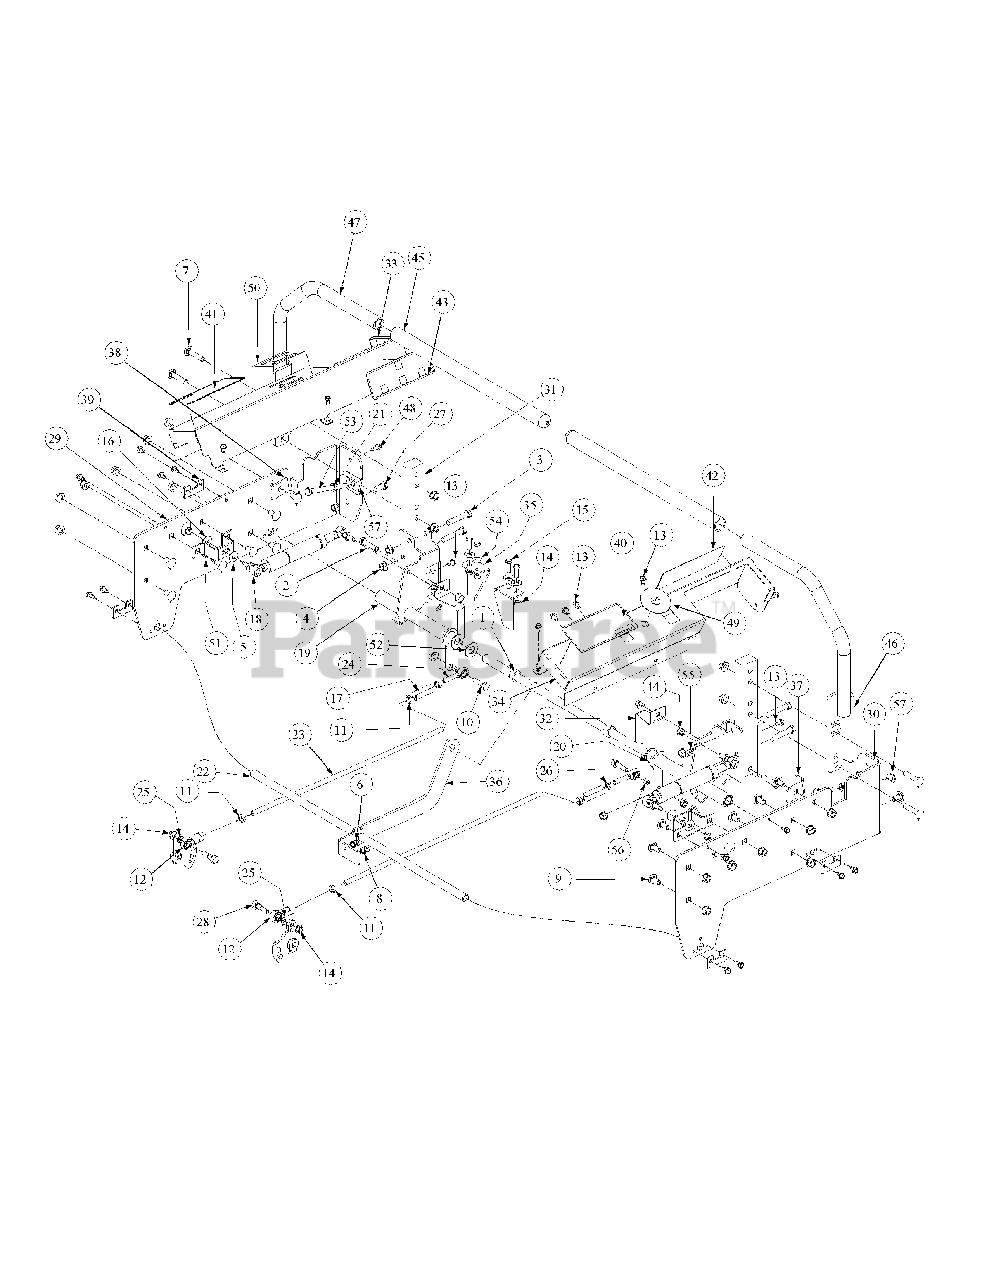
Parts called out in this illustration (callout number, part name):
1	Shaft Collar
2	HHCS, 3/8-16, 2.00
3	HHCS, 3/8-16, 2.25
4	Hex Nut, 3/8-16, Lock Flange
5	External Washer, 3/8
6	HHCS, 1/4-20, .750
7	Hex Carriage Screw, 3/8-16, 1.75
8	Lock Washer, 1/4 Zinc
9	Carriage Bolt, 3/8-16 x .75
10	Capscrew, 3/8-16 x 1-3/4
11	Hex Jam Nut, 3/8-24
12	B/Joint, 3/8-24, Right Hand Female
13	Screw, TT, 1/4-20, 0.5, Hex Index Washer
14	Nut, Lock, Hex Flange, 5/16-18
15	Hex, Cap Screw, 5/16-18 x 3/4
16	Belle Washer, .325 x .930 x .045
17	Turnbuckle
18	Cylinder Return to Neutral
19	Hub Assy, Control LH Bearing
20	Hub Assy, Control RH Bearing
21	Nut, 3/8-16, Jam
22	Shaft Control Brake Steering
23	Rod Connector 3/8 OD x 14.25
24	B/Joint, 3/8-24, Left Hand Female
25	5/16, Lock Washer
26	Nut, 3/8-24, Jam, LH Third
27	HHCS, 5/16-18 x 1.0
28	Screw, Shoulder Control Rod
29	Side Panel, Control, Left
30	Side Panel, Control, Right
31	Mounting Handle
32	Lever, Safety Switch
33	Control Panel, LH
34	Control Panel, RH
35	Switch Mounting Bracket, Lapbar
36	Link Mounting Control Shaft, Bracket
39	Holder Shaft, Park Brake
40	Decal , Right Hand Console
41	Decal, Left Hand Console
42	Decal Right Hand Control
43	Decal, Left Hand Control
44	Nut, Hex, Center Lock, M8
45	Grip, 1.0
46	Lapbar, Weldment, Right Handle
47	Lapbar, Weldment, Left Handle
48	Screw, TT, 1/4-20, 0.75, Hex Index Washer
49	Label, Ignition, 2.5 Diameter
50	Label, Control, Throttle and Choke
51	Bracket Assembly, Mount Dampener
52	Flat Washer, 5/8 Nylon
53	HHCS, 3/8-16, 3.00
54	Flat Washer, 5/16
55	Grease Fitting, 90 degree
56	Spacer, .385ID x .625 OD x >50 Lg
57	U-Nut, 3/8-16, .75
